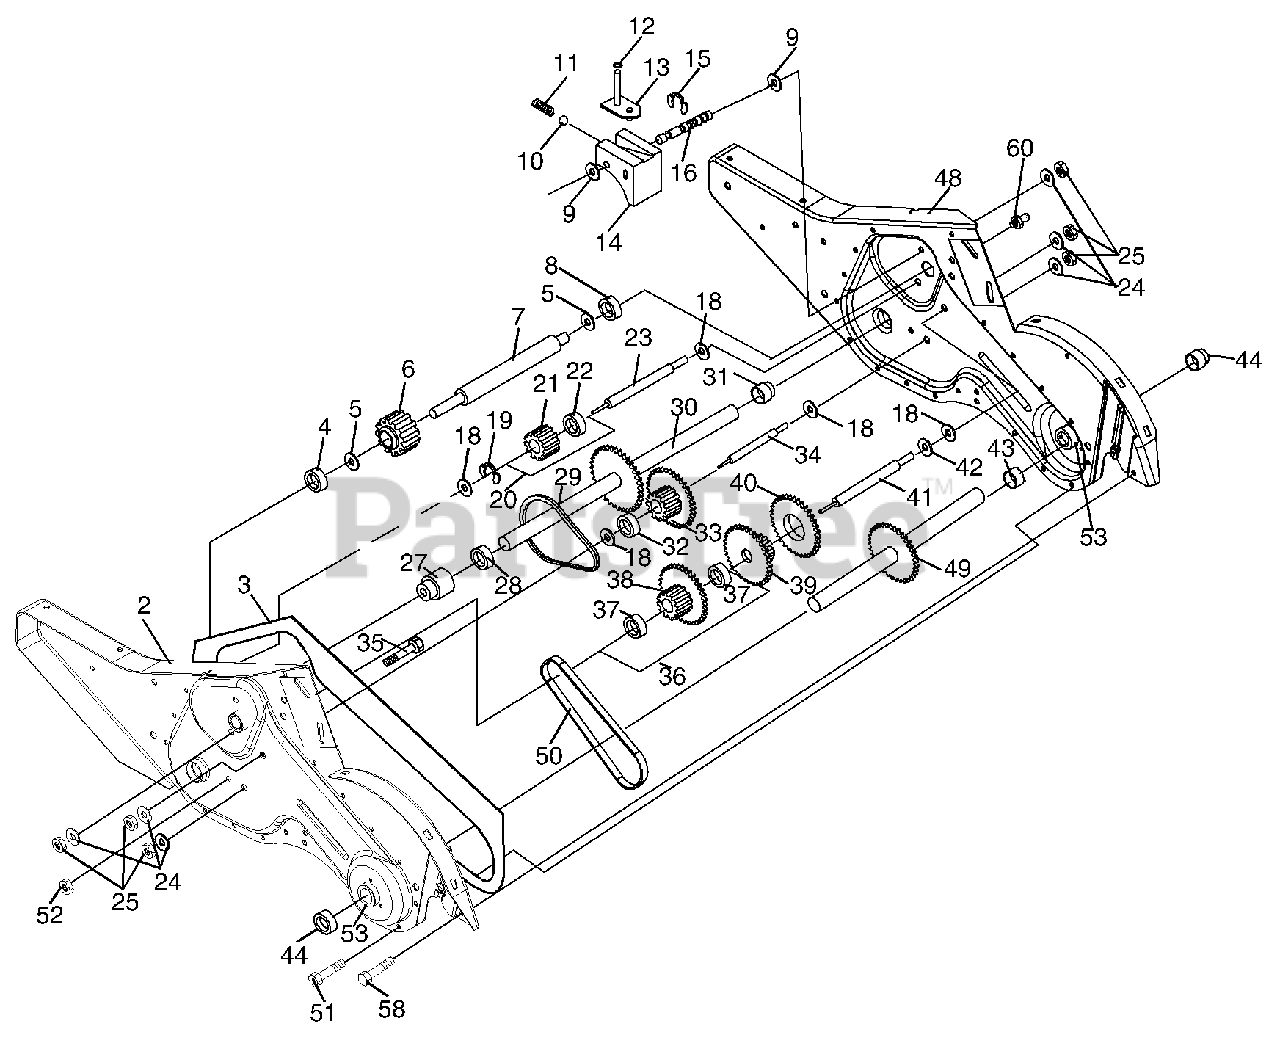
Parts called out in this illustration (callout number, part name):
1	Transmission Assembly
2	Gearcase, L.H. w/Bearing
3	Gasket, Gearcase
4	Bearing, Needle
5	Washer, Thrust 5/8 x 1.10 x 1/32
6	Pinion, Input
7	Shaft, Input
8	Bearing, Needle
9	Washer, Seal
10	Ball, Steel
11	Spring, Shift, Fork
13	Arm, Shift
14	Fork, Shift
15	Ring, Klip
16	Shaft, Shift
19	Ring, Klip
20	Gear, Assembly, Reverse Idler
21	Gear, Reverse Idler
22	Bearing, Needle
23	Shaft, Reverse Idler
24	Washer, Lock 7/16
25	Nut, Hex 7/16-20
27	Bearing, Shaft, Ground Drive L.H.
28	Spacer 0.765 x 1.125 x 1.23
29	Chain #35-50 Pitch
30	Ground Shaft Assembly
31	Bearing, Shaft, Ground Drive R.H.
32	Spacer 0.70 x 1.00 x 1.150
33	Sprocket and Gear Assembly
34	Shaft, Reduction (2nd)
35	Screw, Whiz, Lock 5/16-18 x 3-1/2
36	Sprocket Assembly w/Bearing
37	Bearing, Needle
38	Sprocket, Tine
39	Gear, Cluster, Red 1st & 2nd
40	Gear, Reverse
41	Shaft, Reduction (1st)
42	Washer, Thrust
43	Spacer 1.01 x 1.75 x 0.760
44	Seal Asm, Oil
48	Gearcase, R.H. w/Bearing
49	Shaft, Tine
50	Chain, Roller #50-50 Pitch
51	Screw 1/4-20 x 1/2
52	Nut, Hex 5/16-18
53	Kit, Bearing
58	Bolt Shoulder 1/4-20 unc x .875
60	Fitting Grease
